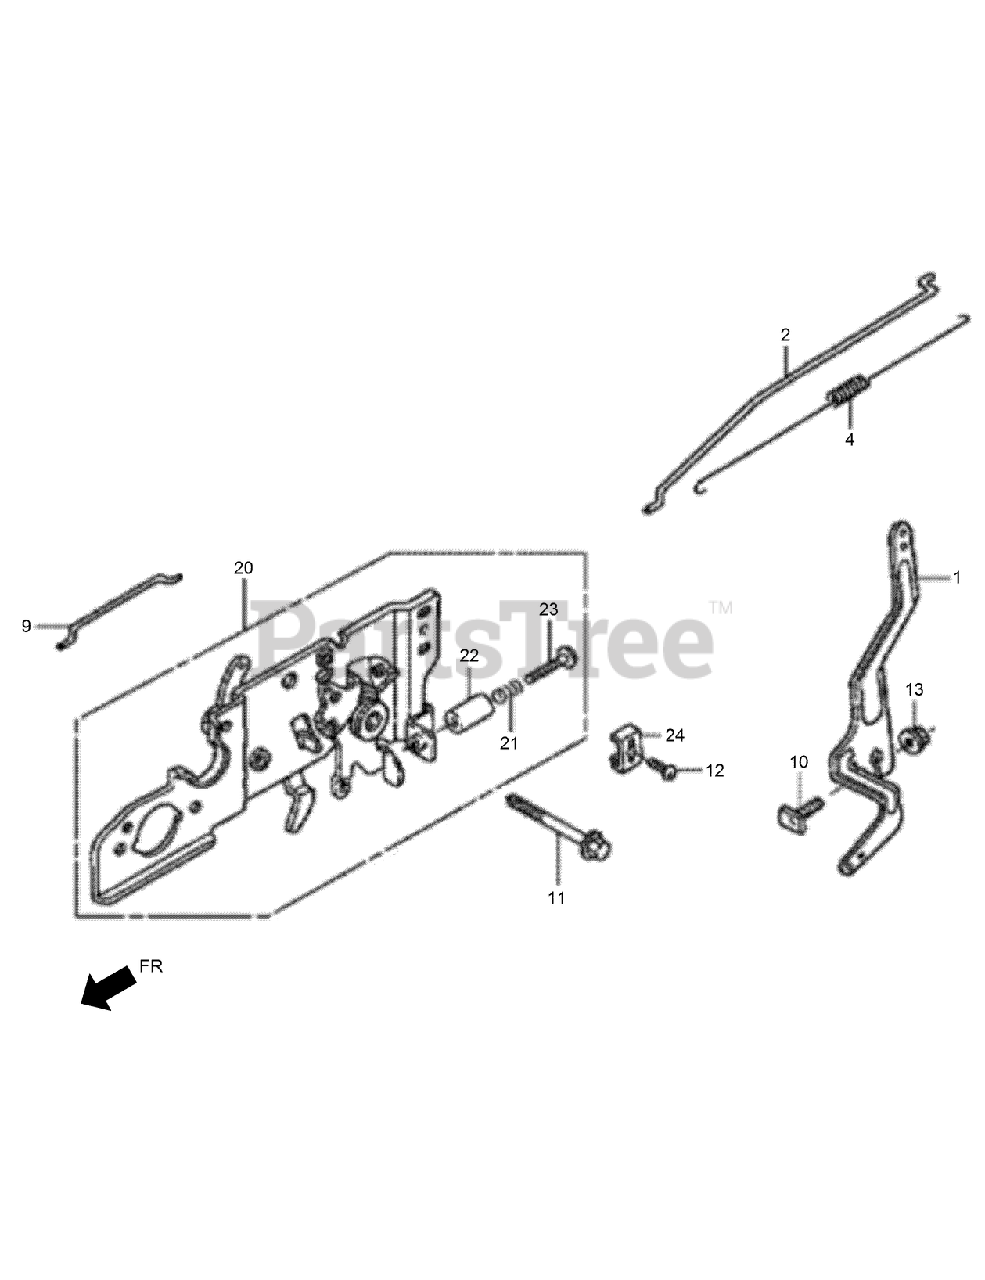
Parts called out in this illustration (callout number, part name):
1	ARM-GOVERNOR
2	ROD-GOVERNOR
4	SPRING-THROTTLE RETURN
9	ROD-CHOKE
10	BOLT-GOVERNOR ARM
11	BOLT-FLANGE-6X50
12	SCREW-PAN-5X16
13	NUT-FLANGE-6MM
20	CONTROL BASE ASM
21	SPRING-CONTROL ADJUSTING
22	COLLAR-STOPPER
23	SCREW-RECESSED-5X28
24	HOLDER-CABLE
